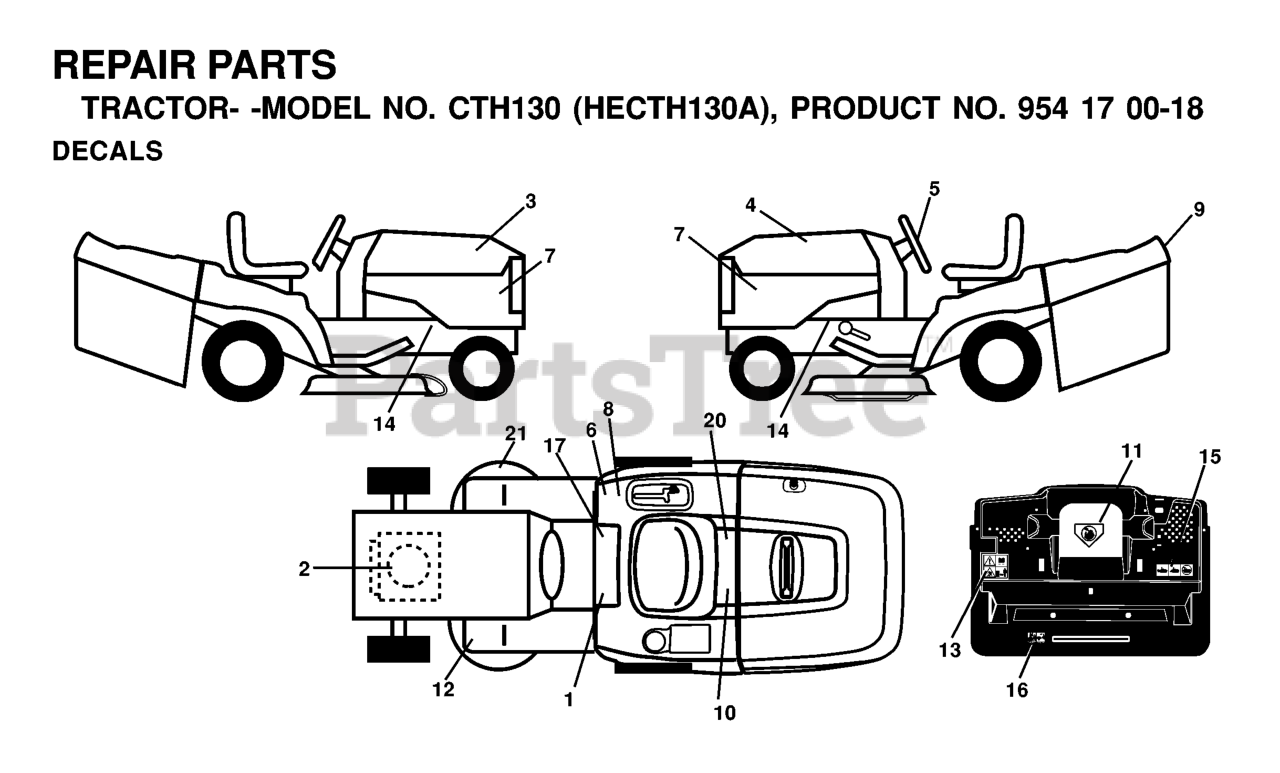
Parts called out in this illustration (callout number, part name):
1	DECAL READ OWNER'S MAN SYMS
2	DECAL HP ENGINE
5	DECAL.WHEEL.STEERING.HUSQ.PERM
6	DECAL CERTIFICATION
7	DECAL PNL SIDE
8	DECAL EUROPE STANDARD CE
9	DECAL FENDER HUSQ
10	DECAL BTRY SYMBOLS
11	DECAL MOWER CUT/FINGER
12	DECAL
13	Decal Warn Back Plate CRD
16	DECAL
17	DECAL PARK BRAKE
20	DECAL.BYPASS.FENDER.CRD.LT.YT
